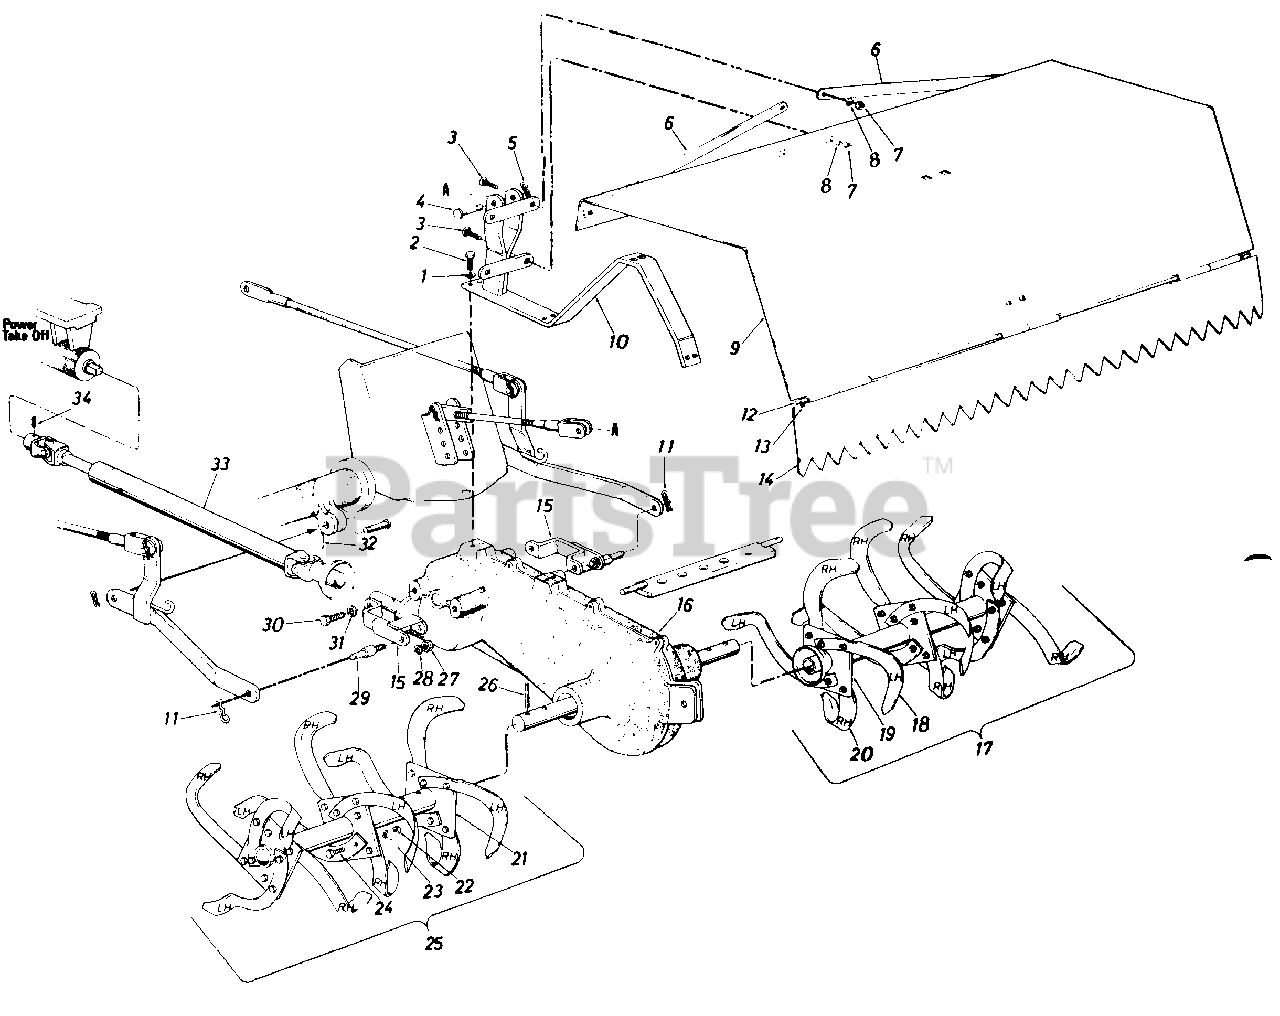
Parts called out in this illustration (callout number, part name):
1	L.-Wash. 1/2" Scr.*
2	Hex Scr. 1/2-13 x 1.25"Lg.*
3	Carriage Bolt 5/16-18 x 1.00" Lg.*
4	Clevis Pin 5/8" Dia. 2.4" Lg.
5	Internal Cotter Pin 5/8" Dia
6	Ti I ler Cover Strap
7	Hex Nut 5/16-18 Thd.*
8	L.-Wash. 5/16 " Scr. *
9	Tiller Cover Ass V
10	Cover Brkt. Ass'y.
11	Internal Cotter Pin 5/8" Dia
12	Cover Flap Rod
13	Cotter Pin 1/8" Dia. x 1.00" Lg. *
14	Cover Flap Ass'y.
15	Tiller Pivot Brkt. Ass'y.
16	Gear Box Ass'y.-Comp.
17	Right Hand Tine Ass'y.-Comp.
18	14" Tine-L.H.
19	Mounting Adapter-R.H.
20	14" Tine-R.H.
21	Mounting Adapter-L.H.
22	Hex Nut 3/8-24 Thd.*
23	L.-Wash. 3/8" Scr.*
24	Hex Scr. 3/8-24 x 1.25" Lg.
25	Left Hand Tine Ass'y.-Comp.
26	Spring Pin Spirol 3/8" Dia. x 2.00" Lg.
27	Hex Cent. L.-Nut 5/8-18 Thd.
28	L.-Wash. 5/8" Scr. *
29	Link Clevis Pin
30	Hex Scr. 5/8-11 x 1.50"Lg.*
31	L.-Wash. 5/8" Scr.*
32	Spring Pin Spirol 5/16" Dia. x 1.75" Lg.
33	Universal Drive Shaft Ass'y.
34	Sq. Hd. Set Scr. 3/8-16 x .50" Lg. Cup
